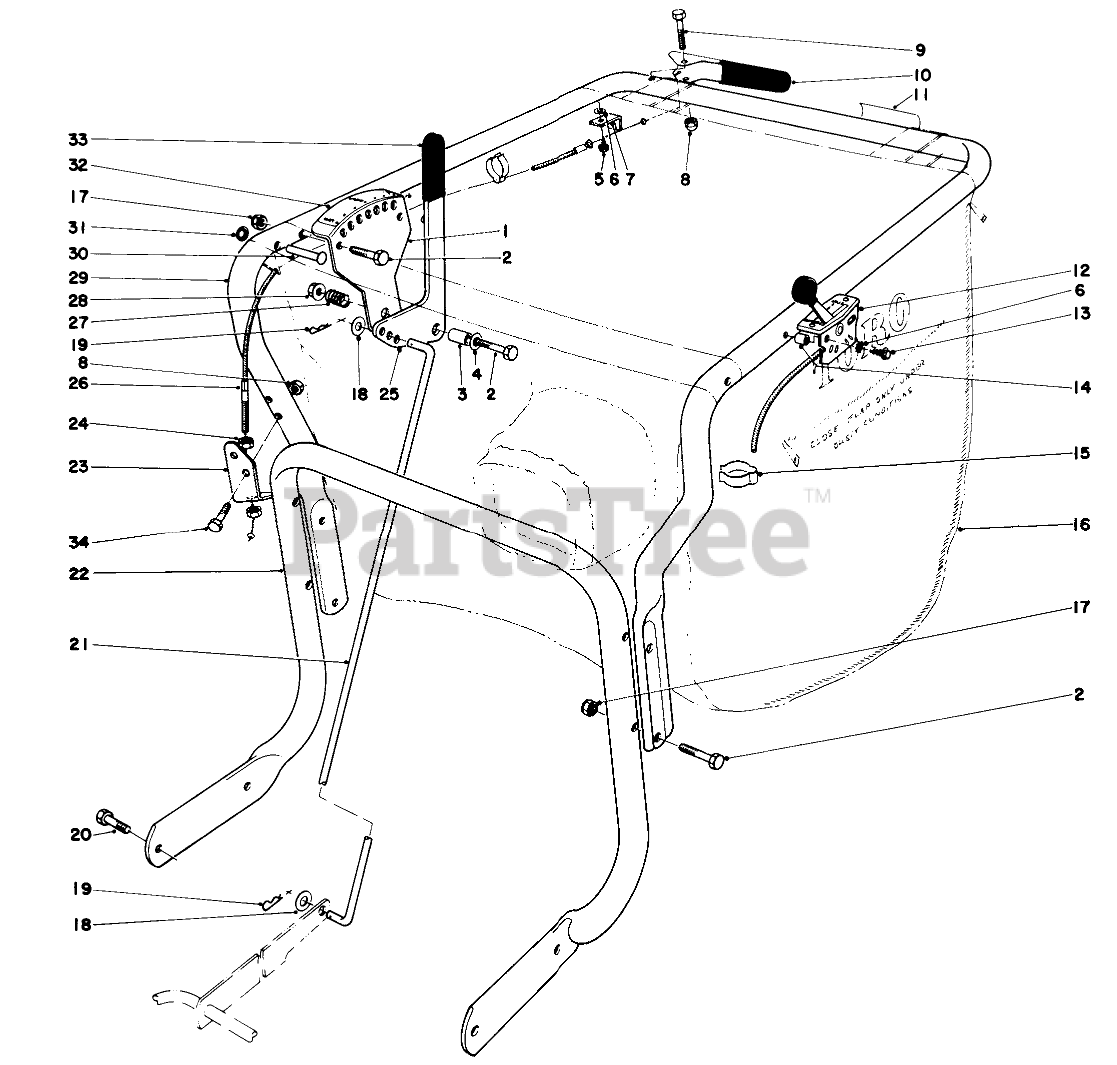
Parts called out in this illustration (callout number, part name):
1	Adjustment Bracket
2	SCREW-HH
3	SPACER
4	WASHER-FLAT
5	SCREW
6	WASHER-LOCK, EXT
7	RETAINING-CLIP
8	NUT-CAP
9	SCREW-HH
10	LEVER W/GRIP
11	TRACTION CONT DECAL
12	THROTTLE CONTROL
13	10-24 X 1 PAN HD SCR
14	SPACER
15	BODEN CLIP
16	Bag-Vacuum
17	NUT-LOCK, CONE
18	WASHER-FLAT
19	PIN-COTTER
20	SCREW-HH
21	HEIGHT ADJ. ROD
22	HANDLE
23	MOUNT-BOWDEN, LOWER
24	NUT-KEPS
25	Handle-Adjustment
26	FWD ASSY CABLE
27	SPRING-COMPRESSION
28	NUT-HF
29	HANDLE-UPPER, VACUUM
30	RIVET
31	NUT-PUSH IN
32	HT ADJ DECAL
33	GRIP-HANDLE
34	SCREW-HH
